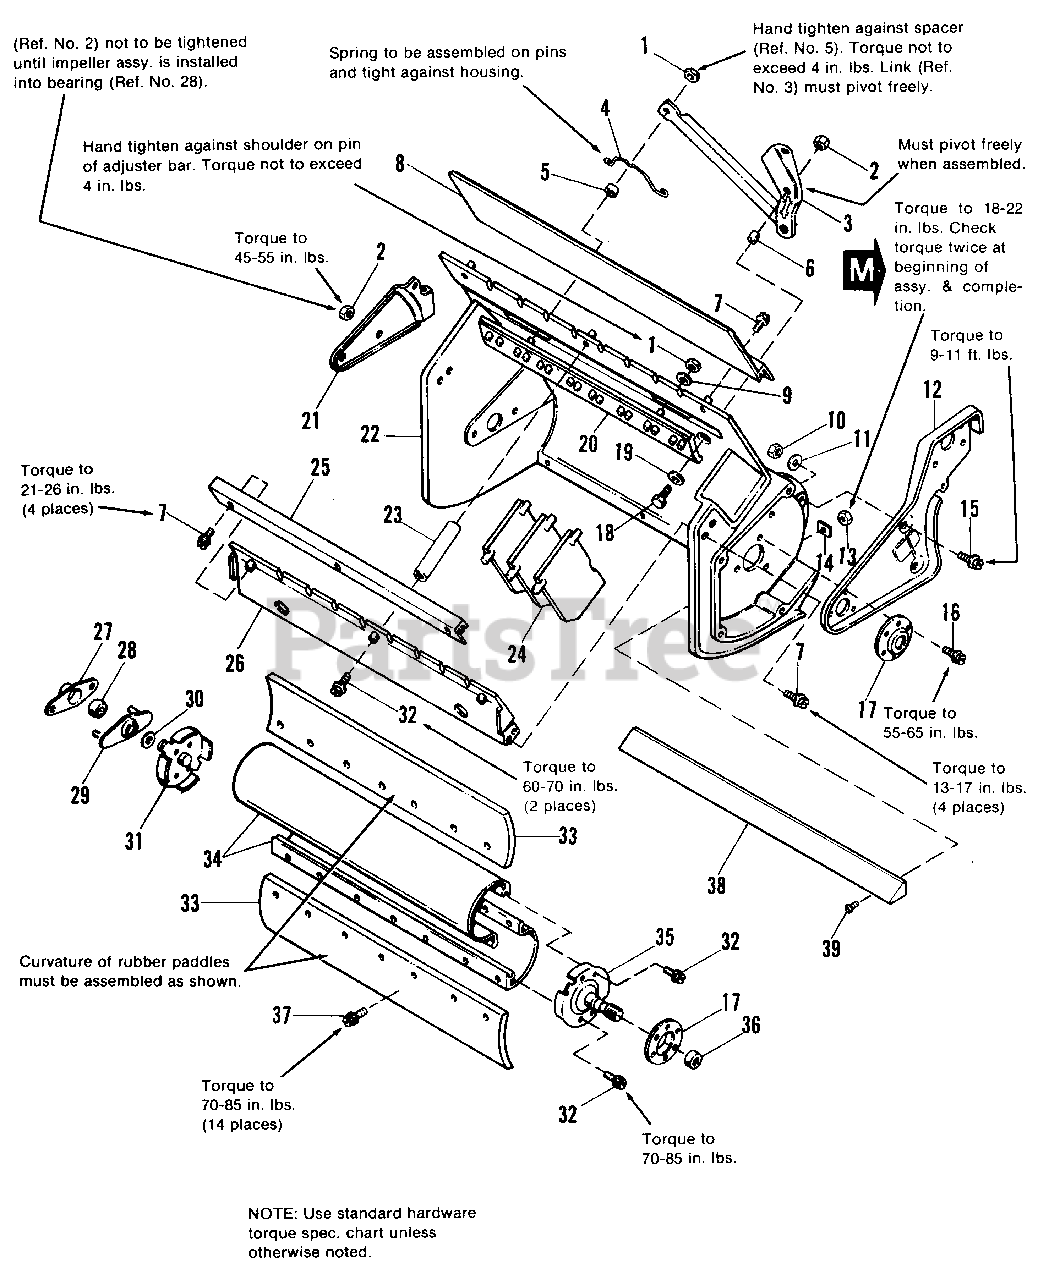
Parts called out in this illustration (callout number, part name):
1	NUT, Self-Threading
2	LOCKNUT, Hex, 1/4-20
3	VANE ASSY., Control
4	SPRING, Detent
7	SCREW, Hex, Wash. Hd., Slotted, #10-24 x 1/2
9	WASHER, Nylon
10	LOCKNUT, Hex, 5/16-18
11	WASHER, Plain, 5/16
13	NUT, Nylon Insert, #10-24
15	CAPSCREW, Hex Hd., 5/16-18 x 3/4
16	SCREW, Hex, Wash. Hd., #10-14 x 5/8
17	RETAINER, Bearing
18	CAPSCREW, Hex Hd., 1/4-20 x 1
19	WASHER, Plain, 1/4
20	BAR, Adjustment
21	BRACKET, R.H.
22	HOUSING, Impeller
26	MOUNT, Front
29	FLANGE ASSY.
31	FLANGE ASSY., R.H.
32	SCREW, Hex Wash. Hd., Slotted, #10-14 x 1
34	DRUM, Impeller
35	FLANGE ASSY., L.H.
37	SCREW, Hex Wash. Hd., Taptite, 1/4-20 x 1-1/8
39	SCREW, Mach., Flat Hd., #10-24 x 1
